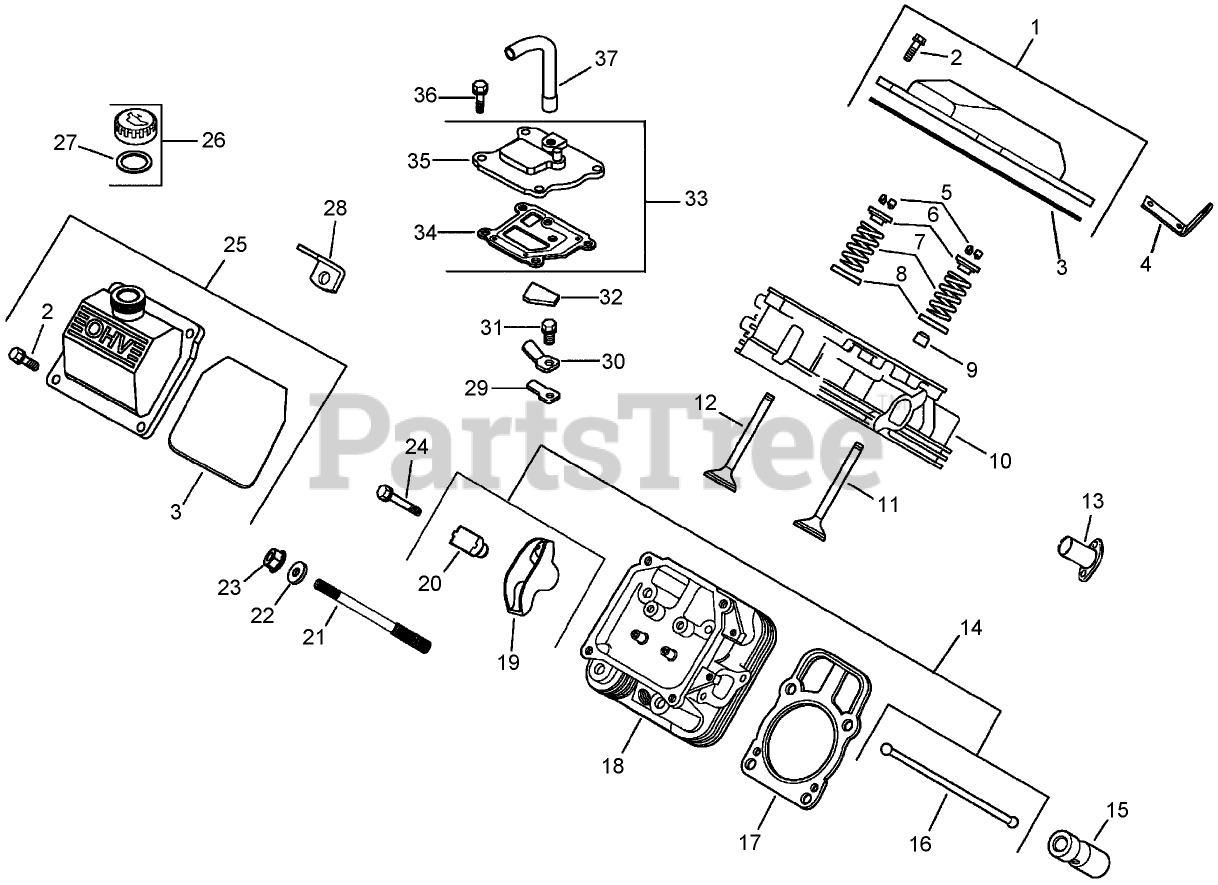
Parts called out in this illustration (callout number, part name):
1	Valve Cover Kit (Includes 2, 3)
2	SCREW-FLANGE (M6X1.0X30)
3	O-Ring
4	STRAP-LIFTING
5	RETAINER KIT
6	CAP-SPRING, VALVE
7	SPRING-VALVE
8	RETAINER-SPRING
9	SEAL-STEM, VALVE
10	CYLINDER HEAD ASM
11	VALVE-INTAKE (STD)
11	VALVE-INTAKE (.25)
12	VALVE-EXHAUST (STD)
12	VALVE-EXHAUST (.25)
13	Liner-Port, Exhaust
14	Valve Train Kit (Includes 16, 19, 20)
15	HYDRAULIC VALVE LIFTER KIT
16	ROD-PUSH
17	Cylinder Head Gasket Kit (Includes 22, 23)
18	CYLINDER HEAD ASM
19	ARM-ROCKER
20	Pivot-Arm, Rocker
21	STUD (M8X1.25xM10X1.5x105MM)
22	WASHER-FLAT (8.6 MM)
23	NUT-FLANGE (M8X1.25)
24	SCREW-FLANGE (M6X1.0X34)
25	Valve Cover Kit (Includes 2, 23)
26	Oil Fill Cap ASM (Includes 27)
27	O-RING
28	Strap-Lifting
29	REED-BREATHER
30	RETAINER-REED
31	SCREW-HHFTF (M5X.80X10)
32	Filter-Breather
33	Breather Kit (Includes 34, 35)
34	GASKET-BREATHER
35	COVER-BREATHER
36	SCREW-HHFTF (M6X1.0X20)
37	Hose-Breather
